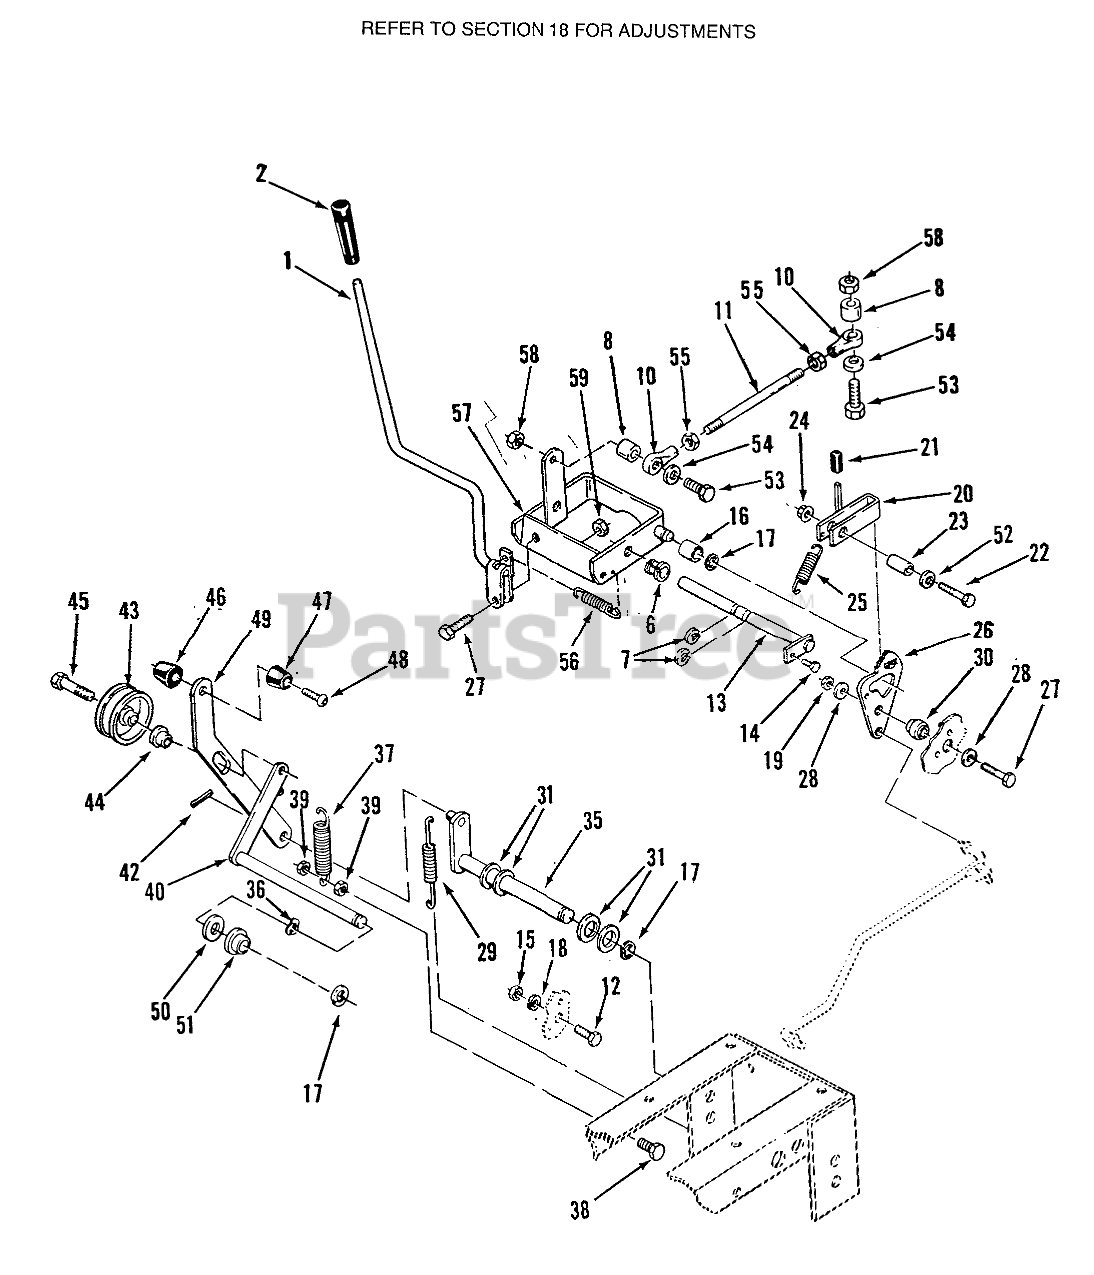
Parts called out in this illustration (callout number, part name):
1	Motion Control Lever (VIN-S 31-18OE01, 31-20OE01, C1-20OE01)
2	KNOB
3	Detent-Motion Control Lever
4	H H C S
5	Nut
6	NYLINER BUSHING
7	E Ring
8	Spacer
10	ASSY ROD END
11	ROD-CONTROL
12	Bolt
13	ASSY-ROD CAM PIVOT
14	SCREW
15	Nut
16	BEARING-CAM RETURN
17	E Ring
18	LOCKWASHER
19	Nut
20	PAWL HDL ASSY B
21	VALVE LEVER GRIP
22	Bolt
23	SPACER
24	LOCKNUT-FLANGE
25	Spring
26	Cam Plate
27	Bolt
28	Washer
29	SPRING-EXTENSION
30	Spacer
31	Washer
35	ASSY-BRAKE LEVER
36	WASHER-WAVE
37	SPRING-EXTENSION
38	Bolt
39	Nut
40	ASSY-ARM/ROD WA
42	Cotter Pin
43	PULLEY-IDLER
44	SPACER-BRAKE LINK
45	BOLT-SPECIAL HEX
46	KNOB
47	KNOB
48	BOLT-4
49	Handle
50	Washer
51	BUSHING-FLANGED
52	Washer
53	Bolt 1/4-20 X 1 1/2
55	Jam Nut 1/4-28
56	SPRING
57	Cam Comtrol
58	NUT
